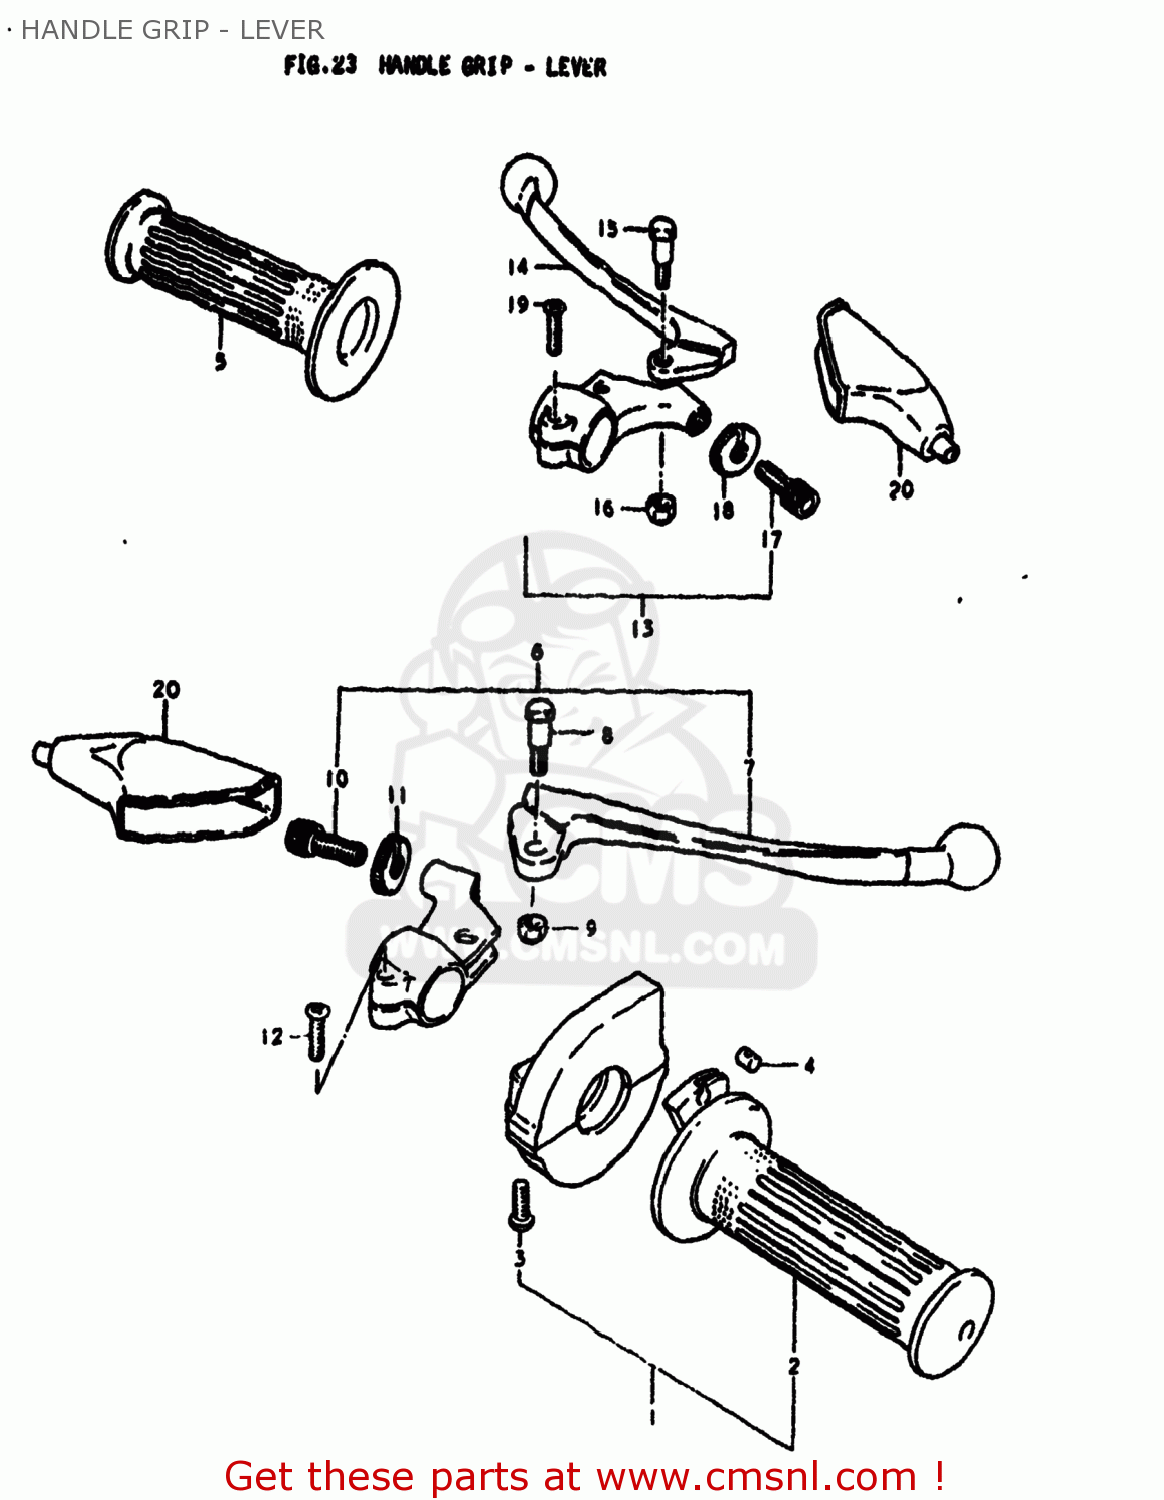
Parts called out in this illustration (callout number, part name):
1	GRIP ASSY,THROTTLE
2	GRIP,THROTTLE
3	SCREW
4	PIECE,THROTTLE END
5	GRIP,LEFT
6	LEVER ASSY,BRAKE
7	LEVER,BRAKE
8	BOLT,LEVER
9	NUT 6MM
10	ADJUSTER,CABLE
11	NUT,CABLE ADJUSTER
12	SCREW
13	LEVER ASSY,CLUTCH
14	LEVER,CLUTCH
15	BOLT,LEVER
16	NUT 6MM
17	ADJUSTER,CABLE
18	NUT,CABLE ADJUSTER
19	SCREW
20	COVER,CLUTCH LEVER
